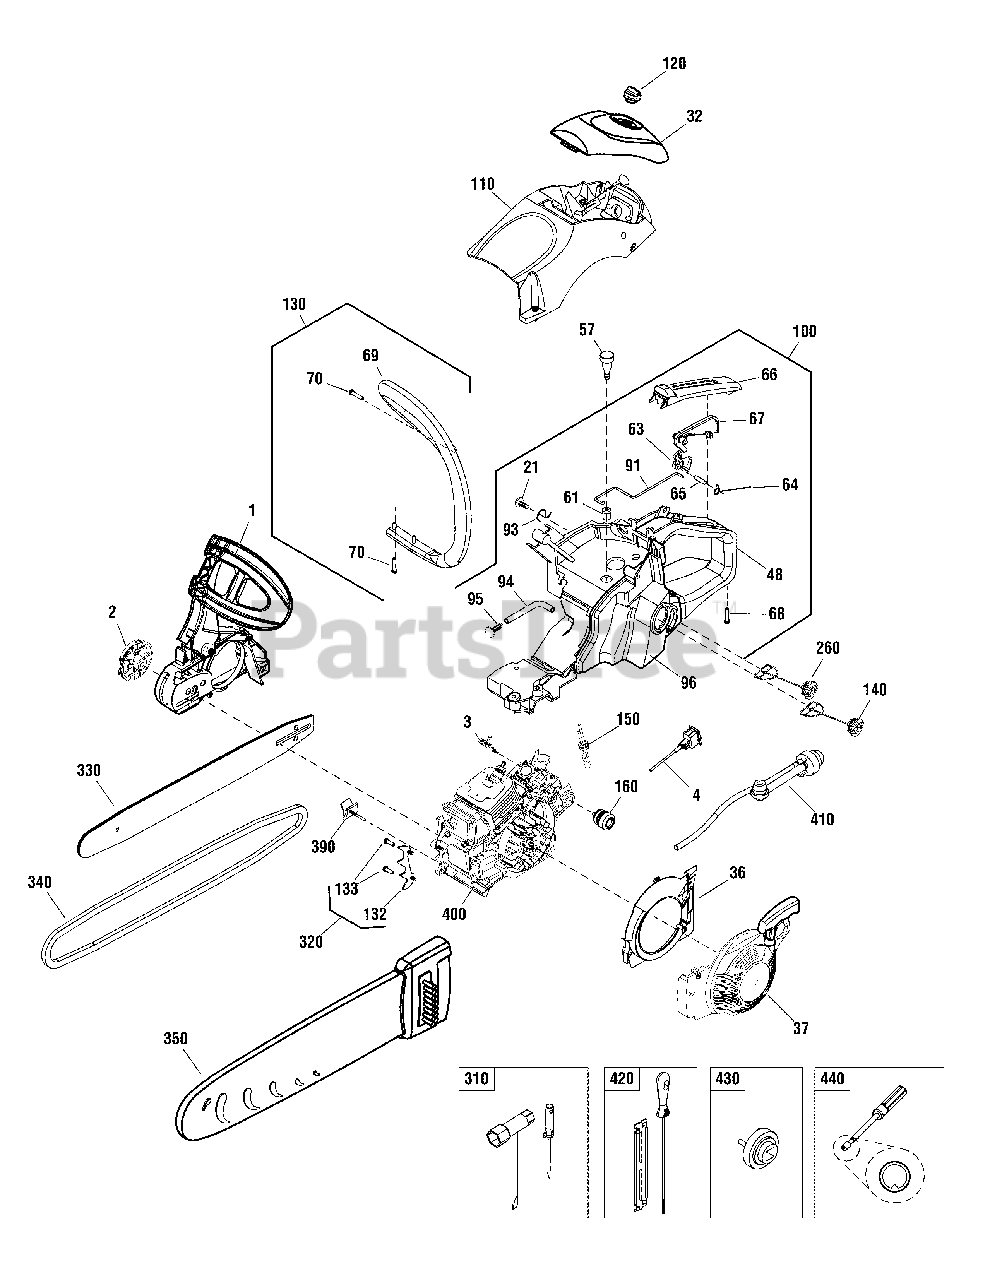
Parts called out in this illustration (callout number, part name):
1	CHAIN BRAKE ASSEMBLY, Red
1	CHAIN BRAKE ASSEMBLY, Silver
2	EASY TENSION RATCHET ASSEMBLY
3	SPRING
4	SWITCH, Off
21	SCREW, ST4.2 x 9.5
32	COVER, Air Filter, Pewter
32	COVER, Air Filter, Blue
36	COVER, Guide Flow
37	STARTER ASSEMBLY, Red
37	STARTER ASSEMBLY, Silver
48	BASE ASSEMBLY
57	BALANCER ASSEMBLY
61	GROMMET
63	TRIGGER
64	SPRING, Torsion, Trigger
65	PIN, 5 x 24
66	COVER, Rear Handle
67	PRESENCE TRIGGER
68	SCREW, ST4.8 x 25
69	HANDLE ASSEMBLY, Front
70	SCREW, Tapping, ST4.8 x 25
91	THROTTLE LINK
93	CIRCLIP
94	TUBE, Vent, 3.5 x 6.5 x 80
95	SCREW, ST4.2 x 14
96	TANK, Fuel
100	HANDLE ASSEMBLY, Rear, Red
100	HANDLE ASSEMBLY, Rear, Silver
110	COVER ASSEMBLY, Upper, Charcoal Gray
110	COVER ASSEMBLY, Upper, Blue
120	KNOB, Air Filter
130	HANDLE ASSEMBLY, Front
132	BUMPER, Spiked
133	SCREW, M5 x 10
140	FUEL CAP ASSEMBLY
150	FUEL FILTER ASSEMBLY
160	SHOCK BUMPER ASSEMBLY
260	CAP, Oil
310	TOOL PACK
320	SPIKED BUMPER ASSEMBLY
330	BAR, Oregon, 16"
340	CHAIN, Oregon, 16" - 3/8"
350	COVER, Bar
390	CHAIN CATCH ASSEMBLY
400	ENGINE ASSEMBLY, 40cc
410	PRIMER BULB
420	* FILE & GUIDE PACK, 5/32"
430	* TOOL, Clutch Removal
440	* TOOL, Carburetor Adjustment
